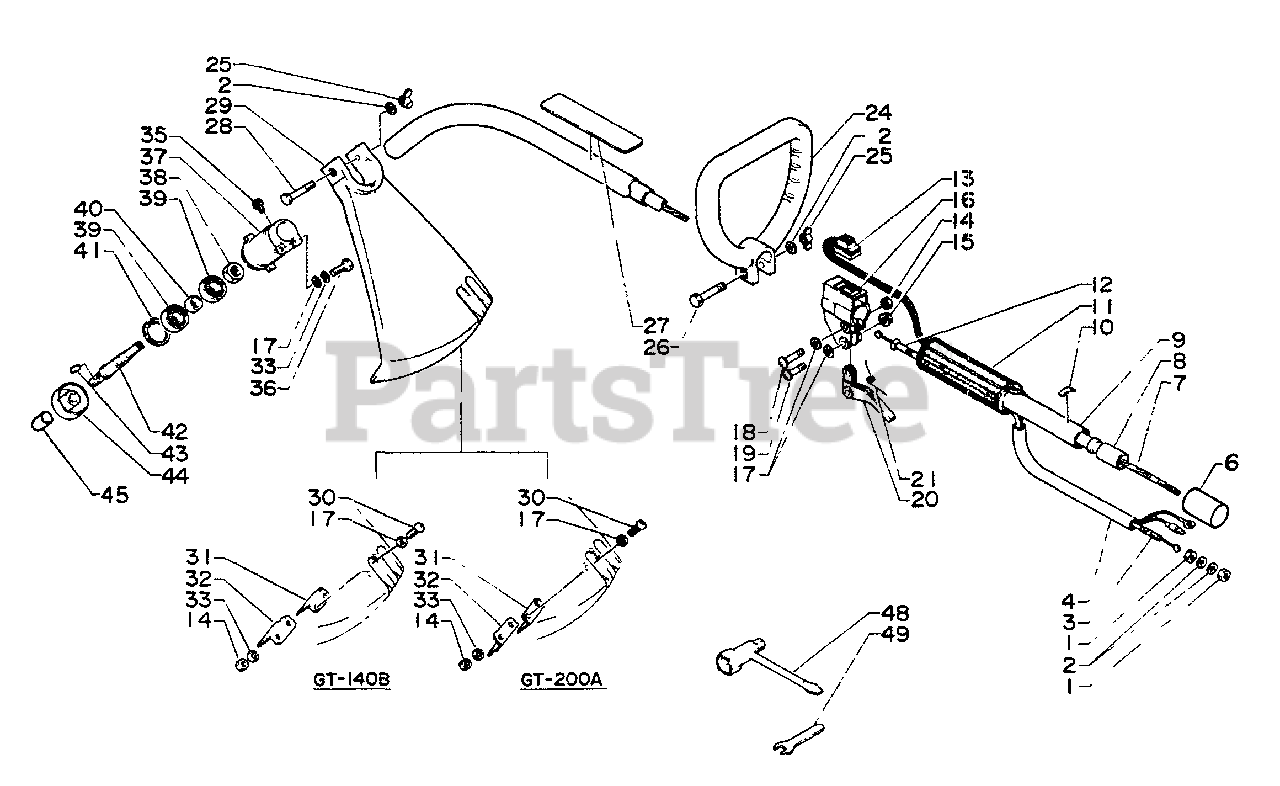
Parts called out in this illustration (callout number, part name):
2	WASHER 6.5×11.5×0.8
3	CABLE, THROTTLE
4	TUBE
7	DRIVESHAFT - FLEXIBLE
8	BUSHING
9	PIPE, MAIN
10	LABEL - ALIGNMENT
11	GRIP, HANDLE
12	GUIDE, CABLE
13	IGNITION SWITCH ASSY
14	NUT M5
15	LOCKNUT - 5
16	BRACKET, THROTTLE
17	WASHER, FLAT 5.5×10×0.8
18	SCREW 5×30
20	TRIGGER, THROTTLE
21	SPRING, THROTTLE
24	HANDLE ASSY
25	NUT, WING 6
26	BOLT - 6×40
27	LABEL - CAUTION
28	BOLT - 6×50
29	SHIELD
30	SCREW 5×14
31	KNIFE, TRIMMER LINE
33	WASHER, SPRING 5
35	SCREW 4×10
36	BOLT - 5×25
37	CASE, GEAR
38	NUT 12 L.H.
39	BEARING, BALL 6001 DDU
41	RING, SNAP 28
42	SHAFT, GEAR
44	PLATE, ADAPTER - UPPER
48	WRENCH
